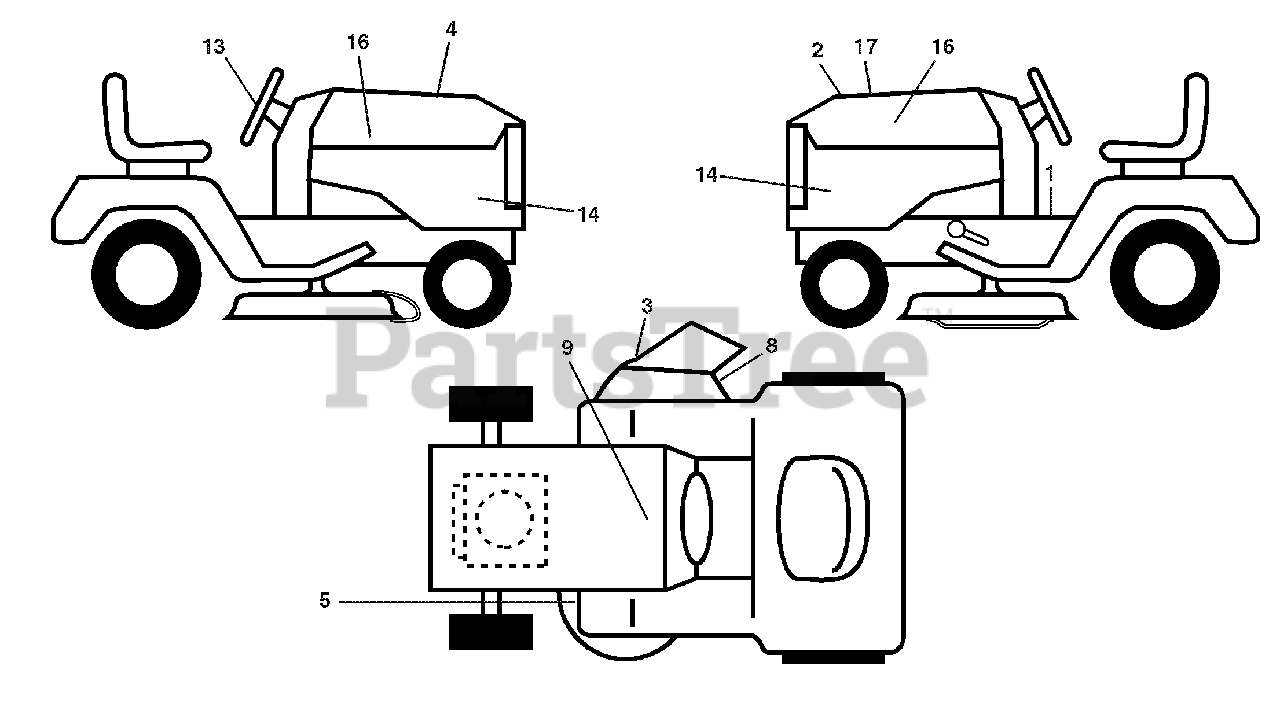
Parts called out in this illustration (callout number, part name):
1	Decal, Operator's
2	Decal, Hood Insert
3	Decal, Warning
4	Decak, Hood Cust Resp.
5	Decal, Caution
8	Decal, Mower Sch.
9	Decal, Battery Dnge/Poi
13	Decal, Steering Whl
14	Decal, Panel Side
16	Decal, Hood Logo
17	Decal, Replacement
17	Decal, Bypass
17	Pad, Footrest, LH
17	Pad, Footrest, RH
17	Manual, Owner's
